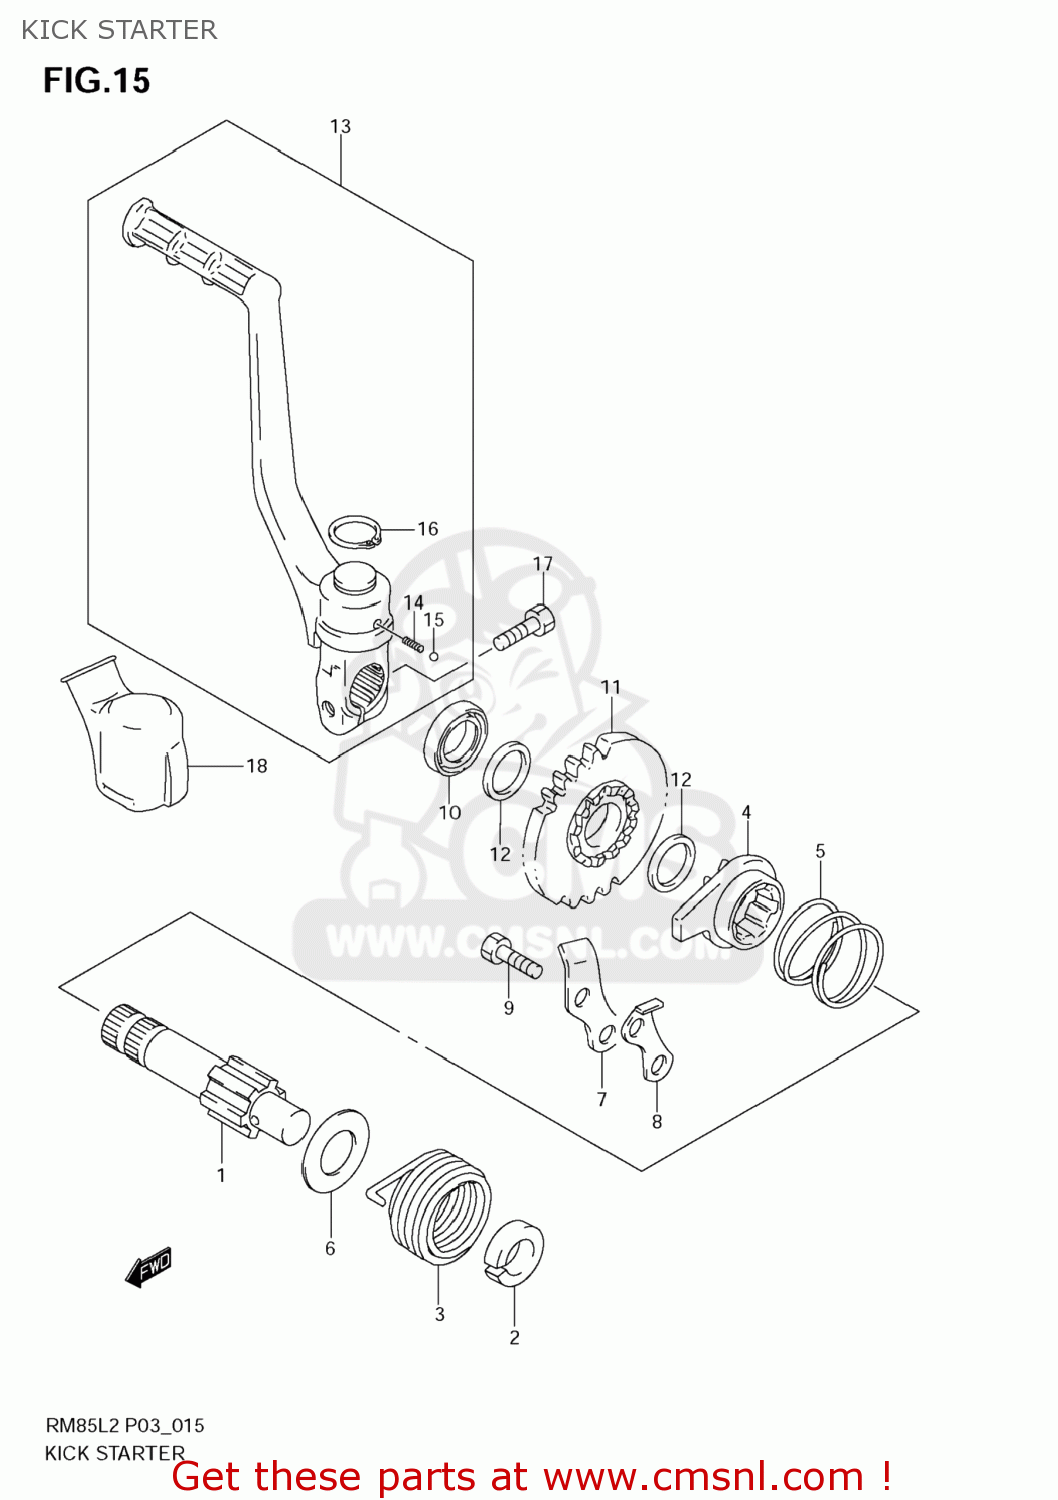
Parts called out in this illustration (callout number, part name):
1	SHAFT,KICK STARTER
2	GUIDE,SPRING
3	SPRING
4	STARTER,KICK
5	SPRING
6	WASHER
7	GUIDE,KICK STARTER
8	STOPPER,KICK STARTER
9	BOLT
10	SEAL,OIL(14X24X6)
11	GEAR,KICK STARTER DRIVE(NT:26)
12	SHIM(14X20X1)
13	LEVER ASSY,KICK STARTER
14	SPRING
15	BALL
16	CIRCLIP
17	BOLT
18	COVER,KICK LEVER JOINT
